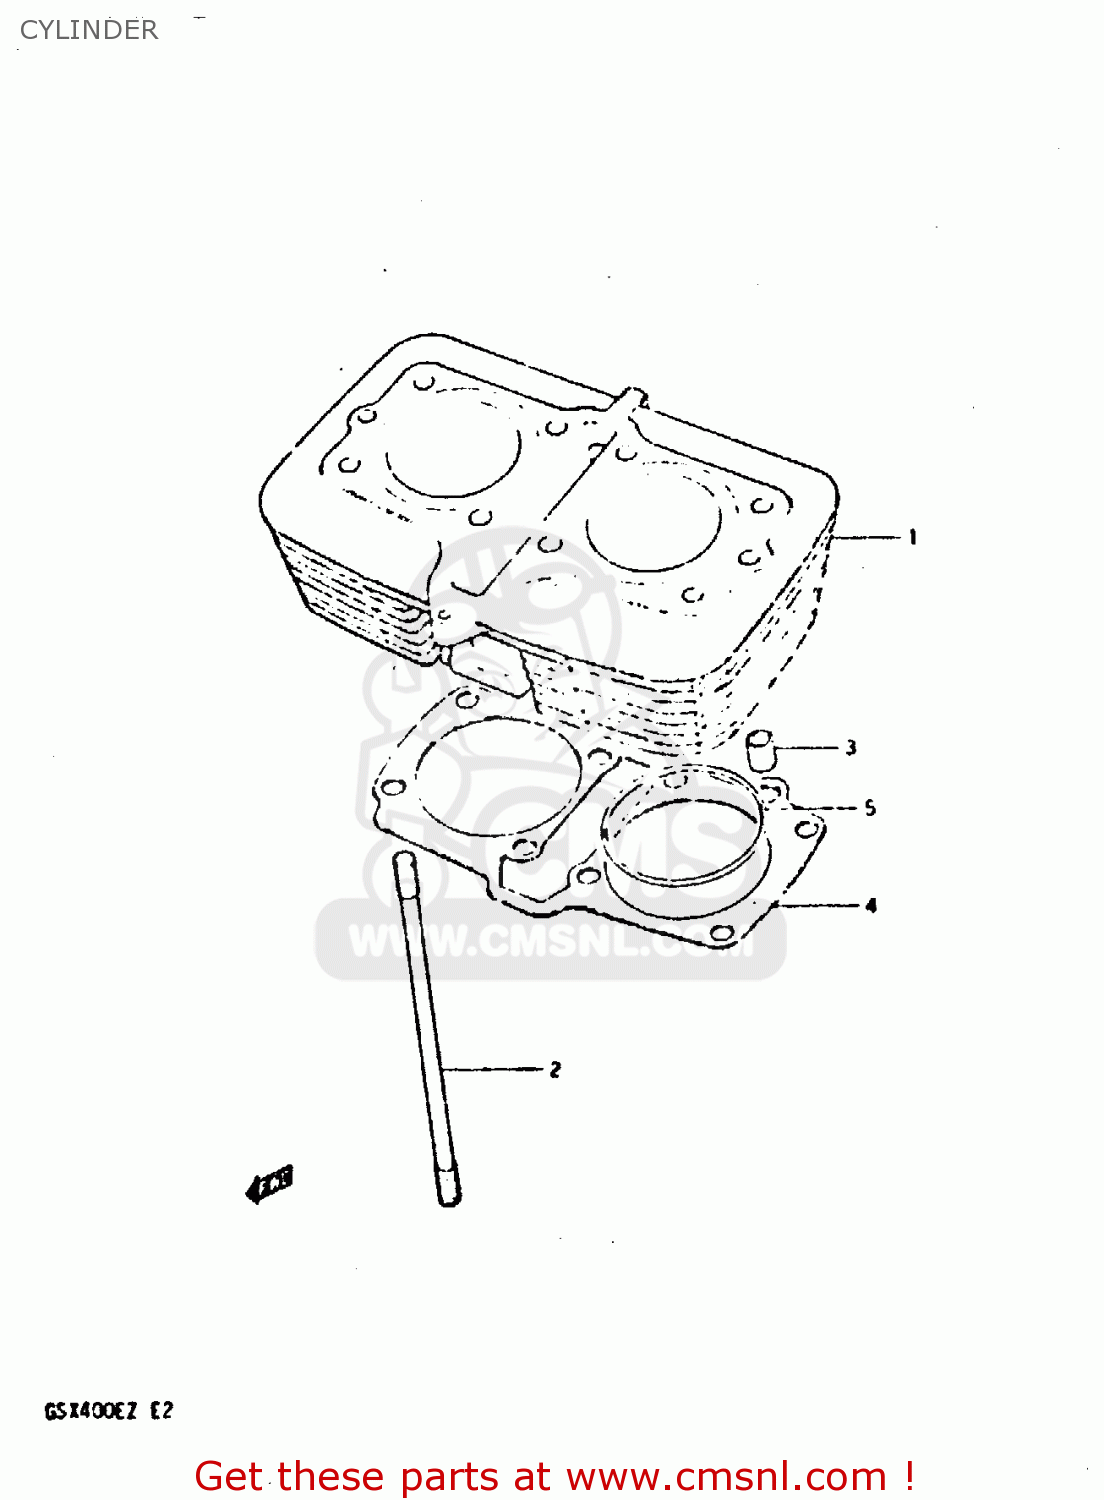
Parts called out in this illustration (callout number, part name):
1	CYLINDER
2	STUD
3	PIN
4	GASKET,CYLINDER (MCA)
5	O RING(D:2,ID:70)
